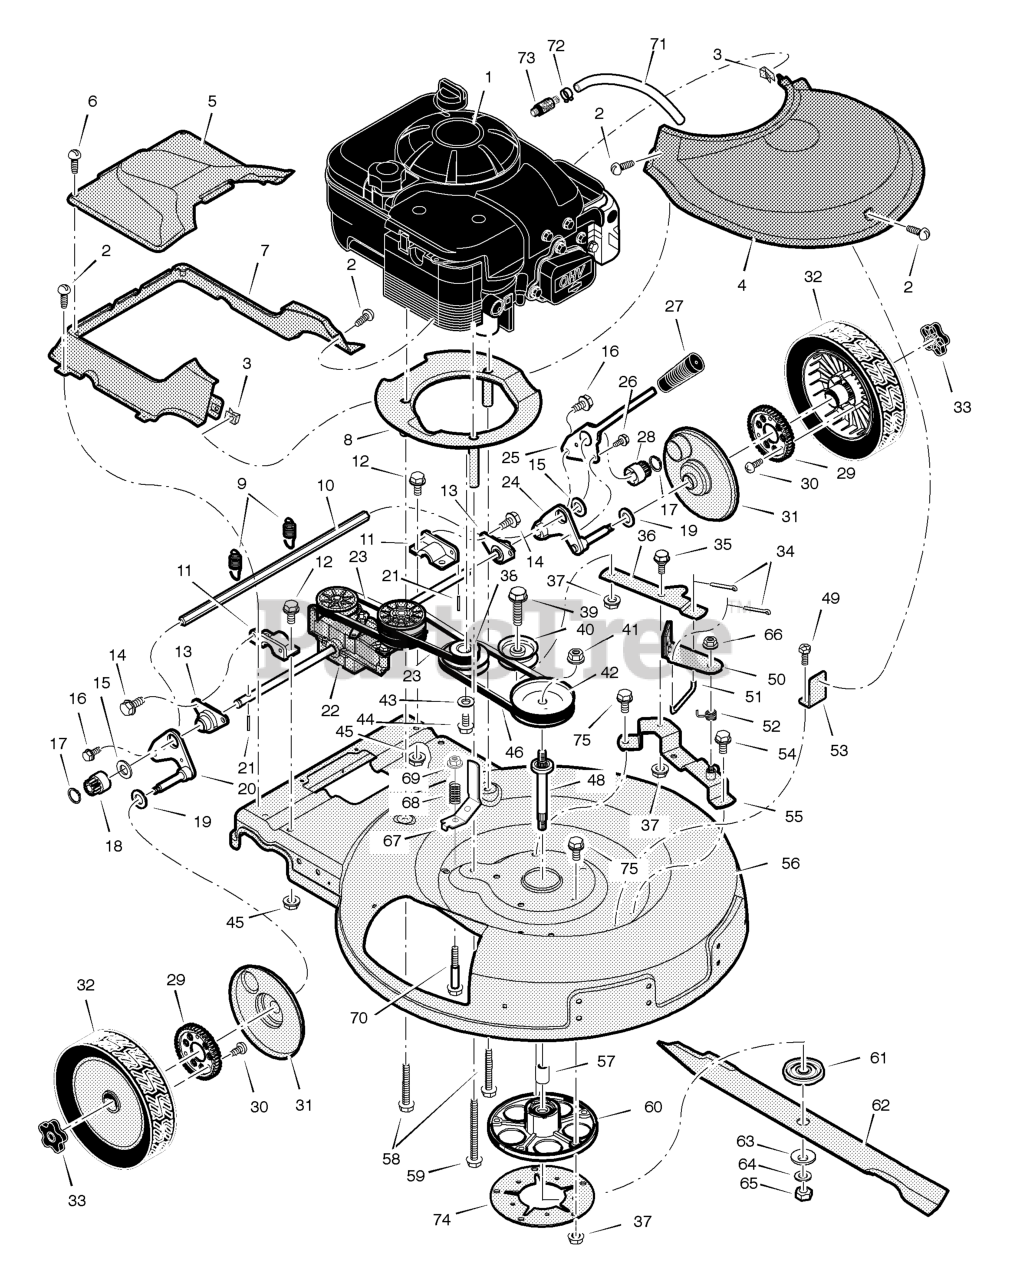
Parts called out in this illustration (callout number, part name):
1	Engine *
3	Tinnerman, "U"
4	Cover, Front
5	Cover, Transmission
7	Cover, Rear
8	Base Assembly, Engine
9	Spring, Extension
10	Crossbar, Rear
11	Bearing, Axle Support
12	Screw
13	Retainer Assembly, Axle Bearing
15	Washer, Thrust
17	Retainer Ring
18	Gear, Right Pinion
19	Washer, Spring
20	Bracket Assembly, Right Axle
21	Pin, Drive
22	Transmission *
23	Belt, Transmission
24	Bracket Assembly, Left Axle
25	Lever, Spring Height Adjuster
26	Screw, Tap
27	Knob, Height Adjuster
28	Gear, Left Pinion
30	Screw, Tap
31	Cover, Dust
32	Wheel, Drive
33	Knob, Axle
34	Pin, Cotter
35	Bolt, Shoulder
36	Idler Arm
37	Nut, Flange
38	Pulley, Engine
39	Screw
40	Pulley, Idler
41	Nut, Blade Pulley
42	Pulley, Blade
43	Washer, Split
44	Screw
46	Belt, Blade Drive
48	Jackshaft
50	Brake Assembly, Blade
51	Link, Blade Brake
52	Spring, Torsion
53	Bracket, Front Cover
55	Support Assembly, Idler & Brake
57	Spacer, Jackshaft
58	Bolt, Short Engine Mount
59	Bolt, Long Engine Mount
60	Mandrel Assembly
61	Adapter, Blade
63	Washer, Cup
65	Nut, Blade Mount
66	Nut
67	Guide, Belt
69	Nut
71	Tube, Oil Drain
72	Clamp, Oil Drain
73	Valve, Oil Drain
74	Support, Jackshaft Housing
